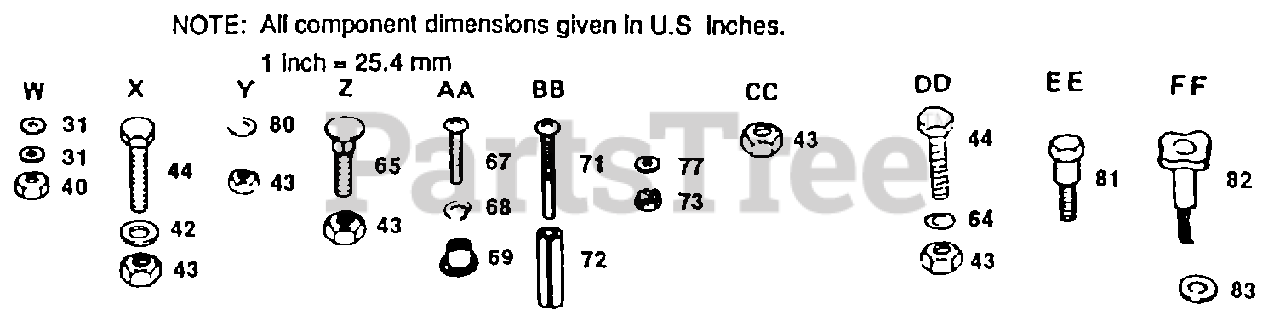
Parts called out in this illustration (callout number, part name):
31	WASHER 9/32 X 3/4 X 16 GA..
42	WASHER
44	BOLT
64	WASHER
65	BOLT
67	SCREW
68	LOCKWASHER
69	WELDNUT
71	SCREW
72	SPACER LT
77	WASHER
80	WASHER
82	"KNOB 1/2"" YT"
83	WASHER
